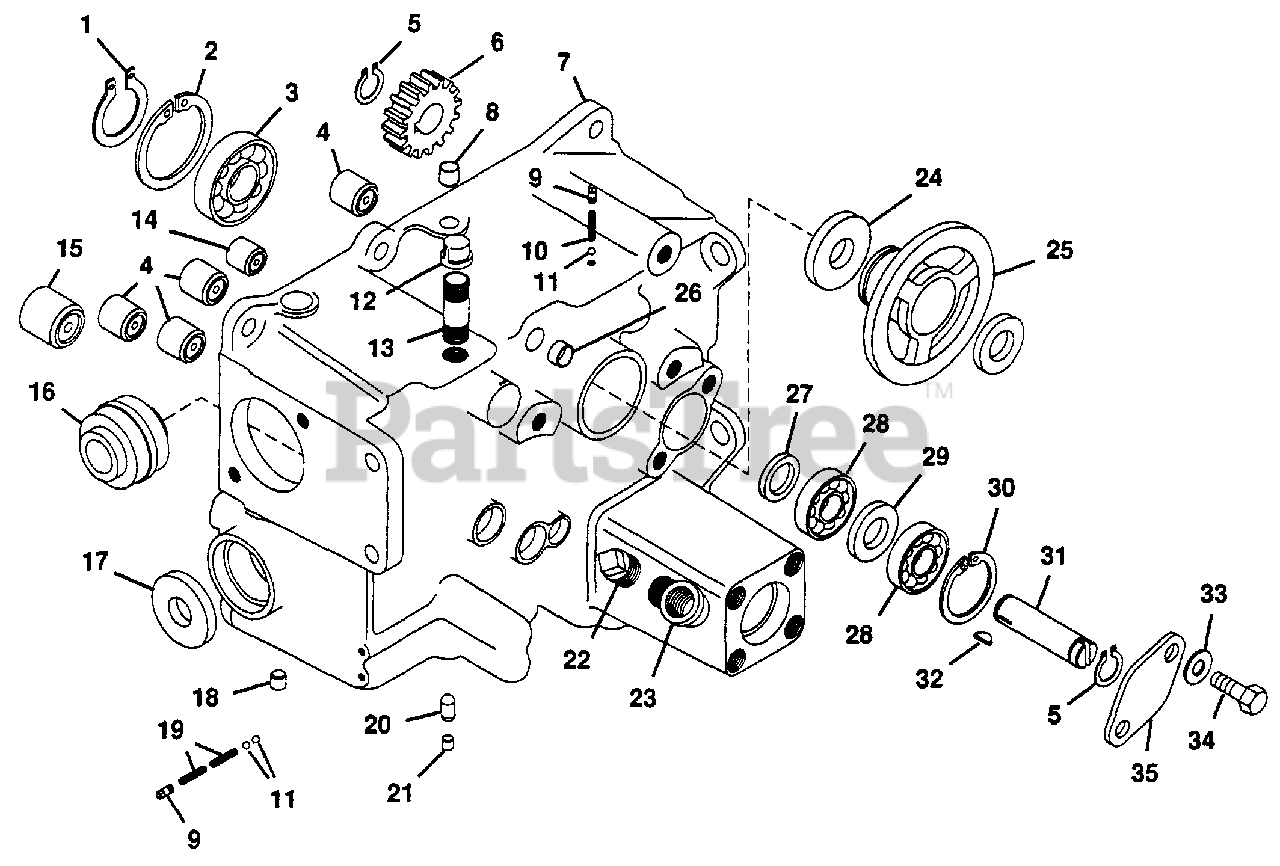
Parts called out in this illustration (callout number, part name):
1	Ring, Retaining 1.969 Shaft
2	Ring, Retaining 3.156 Bore
3	Bearing, Ball 1.968x3.149x.629
4	Bearing, Needle .75x1x.75
5	Ring, Retaining .594 Shaft
6	Gear, Hydraulic Pump
7	Assembly, Transmission Case
8	Plug, Cup .625(4-Spd)
9	Plug, Pipe 1/8
10	Spring(8-Spd)
11	Ball, Steel 5/16(4-Spd)
11	Ball, Steel 5/16(8-Spd)
12	Cap, Pipe 1/2 NPT
13	Nipple, Pipe 1/2x2.5
14	Bearing, Needle .625x.812x.750
15	Bearing, Needle 1.000x1.250x.75
16	Asm, Bearing 1.00x1.98x1.243
17	Seal, Oil 1.375x2.129x.312
18	Plug, Cup 1/2
19	Spring, Comp. 1.50x.30x26 lb/in
20	Pin, Interlock
21	Plug, Cup 3/8
22	Plug, Pipe 1/2
23	Elbow, 1/2 90 Degree Street
24	Seal, Oil 2.250x3.005x.375
25	Hub, Clutch
26	Plug, Cup 3/4
27	Spacer, .276x.620x.750
28	Bearing, Ball .590x1.378x.433
29	Spacer .620x.750x.364
30	Ring, Retaining 1.378 Bore
31	Shaft, Hydraulic Pump
32	Key, Woodruff .125x.375 Hard
33	Washer, Flat .406x.812x.065(4-Spd)
34	Bolt, Hex 3/8-16x.75(4-Spd)
35	Plate, Cover(4-Spd)
